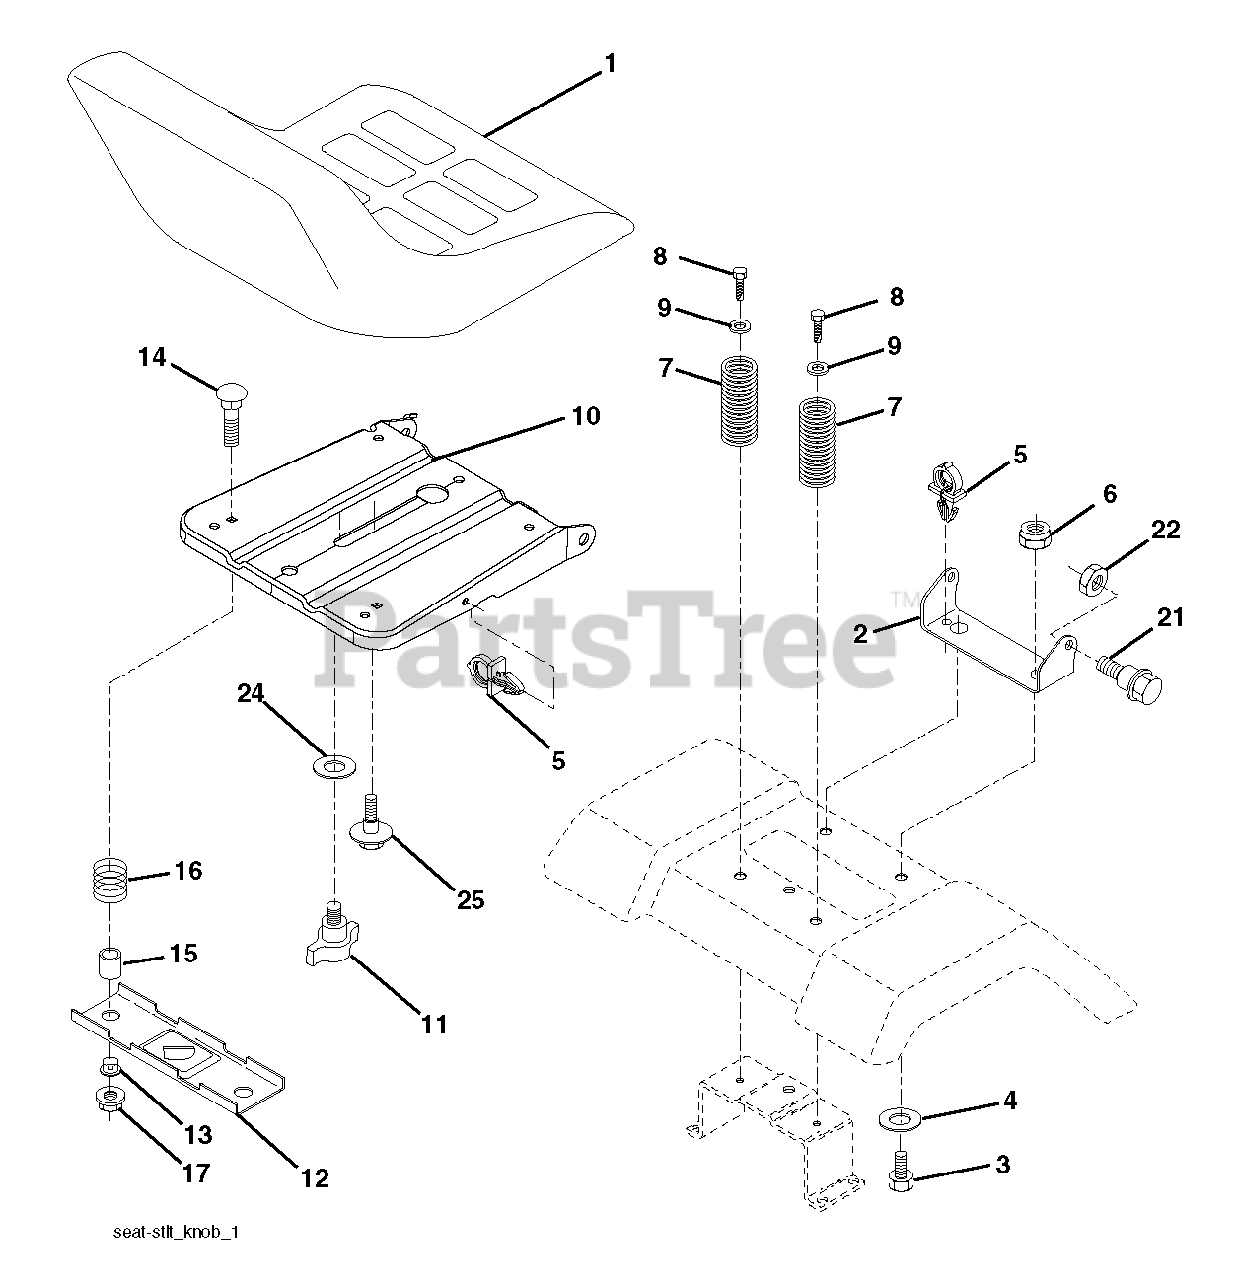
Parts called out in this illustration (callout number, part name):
1	SEAT.XG090.BLK.KB/BLT.NO-LOG
2	SEAT PIVOT BRKT
3	BOLT, HEX 3/8-16X1
4	WASHER PM
5	PUSH CLIP
6	NUT
7	SPRING COMPRESSION
8	SCREW 3/8-16X1
10	PAN.ASM.SEAT.1SLOT
11	KNOB.SEAT.ADJ.WINGNUT
12	BRKT.MNTNG.SWITCH.SEAT.BLACK
14	BOLT.ROUND.HEAD.SQUARE.NECK
15	SPACER SPLIT 28X.96
17	NUT T
21	BOLT.SHOULDER.5/16-18
22	NUT.71038.31-18.HEX.NYLOCK
25	BOLT,SHOULD
